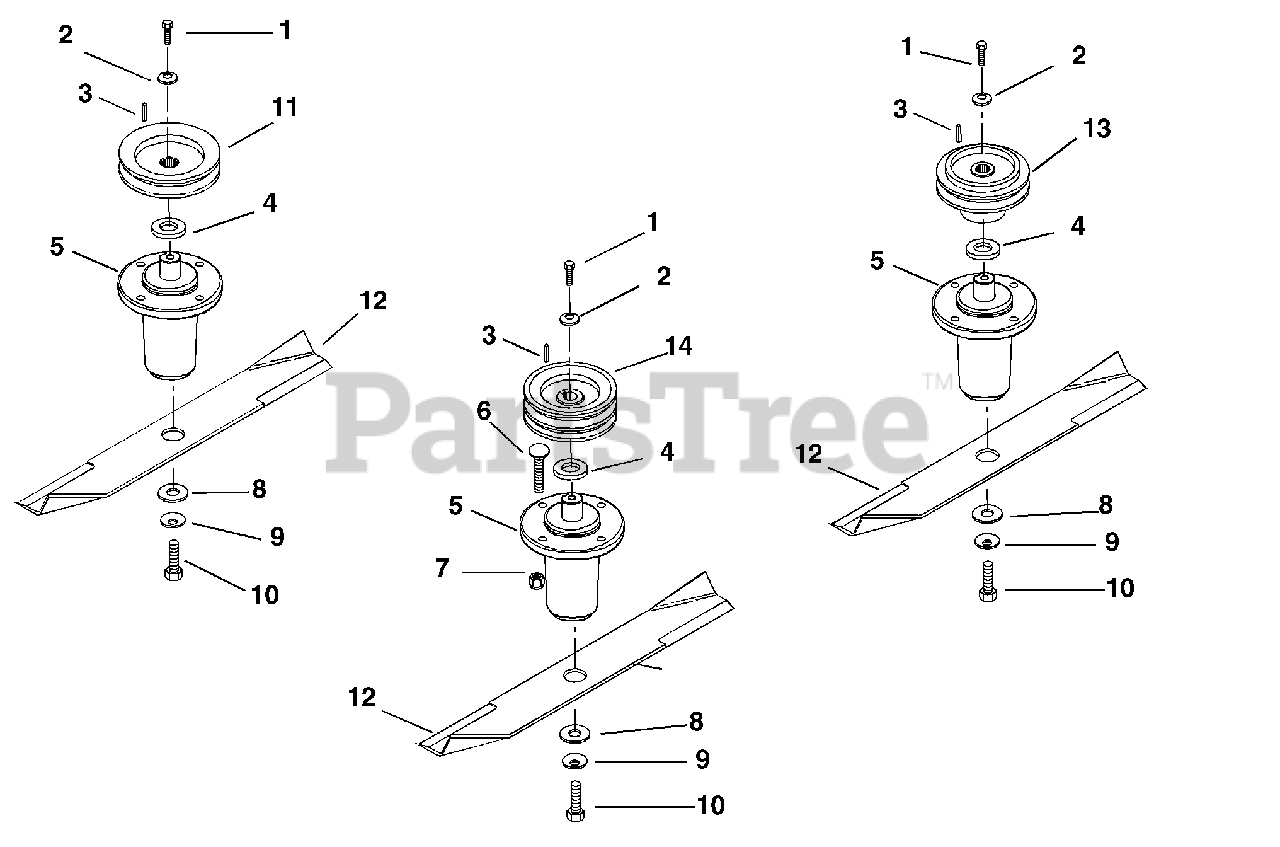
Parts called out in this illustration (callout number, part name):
1	Bolt-Hex .38-16 x 1.00 Grade 8
2	Washer-Cupped Serrated .375
3	Key-Square .25 x 1.00 x .25
4	Slinger-Dust
5	Maintenance Free Spindle Assembly
6	Bolt-Round Head Square Neck .38-16 x 1.50
7	Nut-Locking-Nylon .38-16
8	Washer-Flat Steel .640 x 1.81 x .250
9	Washer-Bellville .63 x 1.625 x .14
10	Bolt-Blade .62-18 x 1.75 Grade 8
11	Weldment, Pulley-V 60" Mower 5.50 x 1.004 with Key (037)
11	Weldment, Pulley-V 50" Mower 3.50 x 1.004 with Key (038)
12	Blade, 60" Mower Tungsten Carbide (037)
12	Blade, 50" Mower Tungsten Carbide (038)
13	Weldment, Pulley-V 60" Mower 5.40X1.004 with caps (037)
13	Weldment, Pulley-V 50" Mower 4.75 x 1.004 with Caps (038)
14	Pulley-60" Mower Double V 2 x 5.660 x 1.004 with Key (037)
14	Pulley-50" Mower Double V 5.20 x 3.50 x 1.004 with Key (038)
